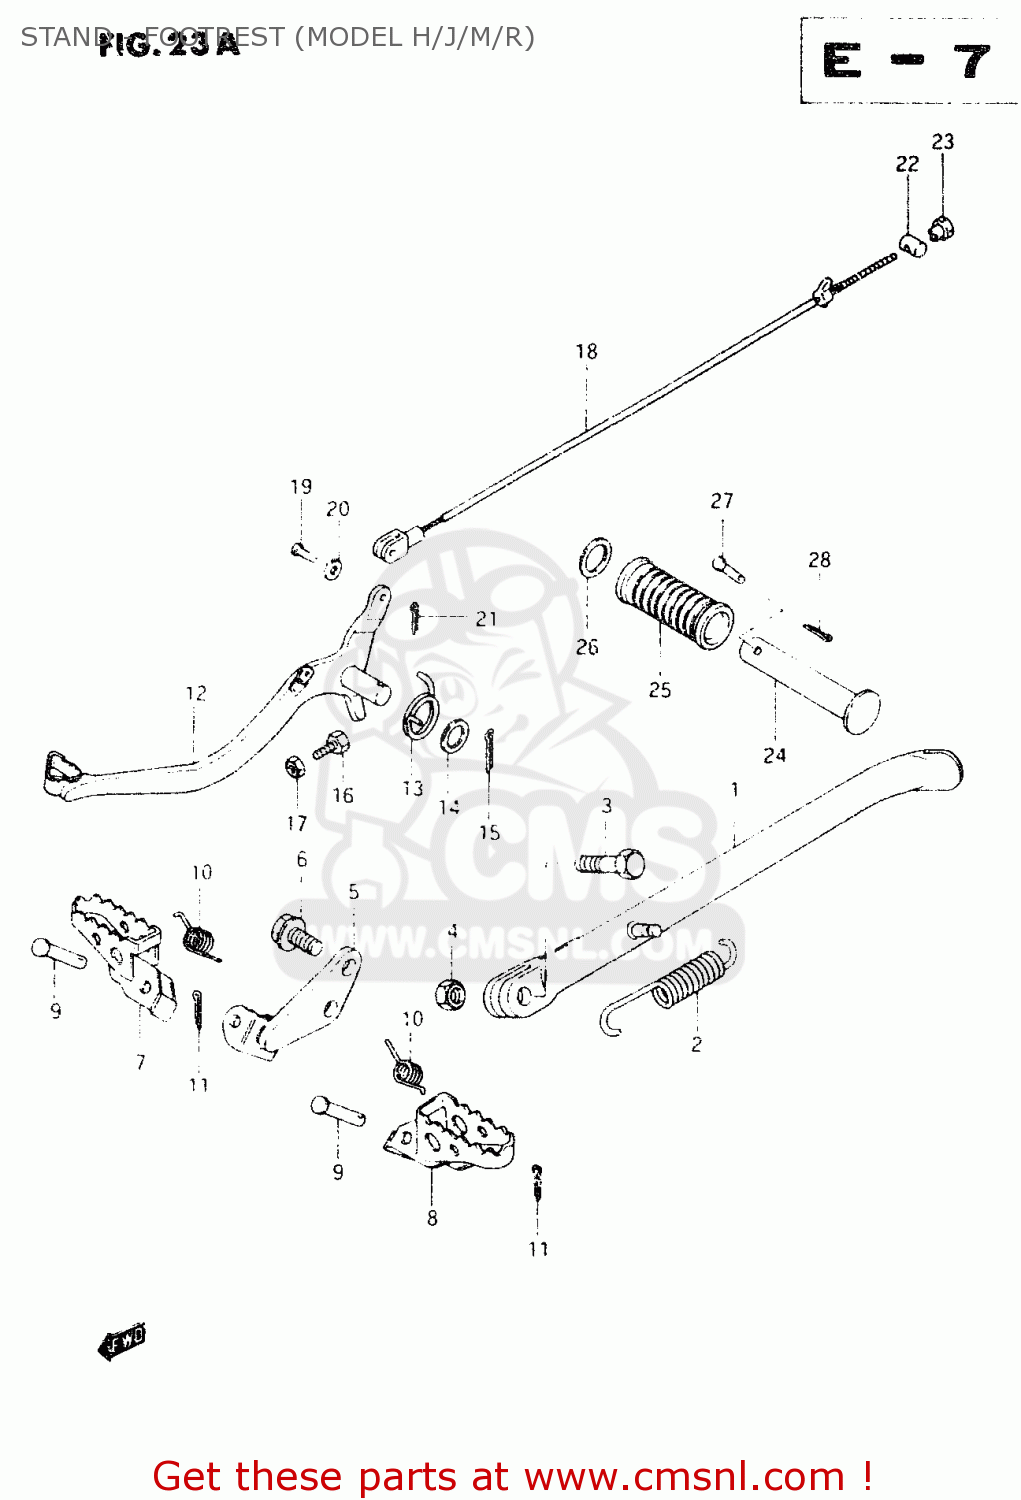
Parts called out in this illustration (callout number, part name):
1	STAND,SIDE
2	SPRING
3	BOLT L:30
4	NUT
5	HOLDER, FOOTREST RH (BLUE)
6	BOLT
7	FOOTREST ASSY,R
8	FOOTREST ASSY,
9	PIN
10	SPRING
11	PIN 25X20
12	PEDAL,BRAKE
13	SPRING
14	WASHER(15.5X26X2.3)
15	COTTER PIN
16	BOLT
17	NUT
18	CABLE,RR BRAKE
19	PIN(L:17.5)
20	WASHER
21	PIN 20X20
22	PIN(11X18)
23	NUT (6MM)
24	BAR,FOOTREST RUBBER
25	RUBBER,PILLION FOOTREST
26	WASHER (19.5X32X2)
27	PIN
28	PIN 20X20
